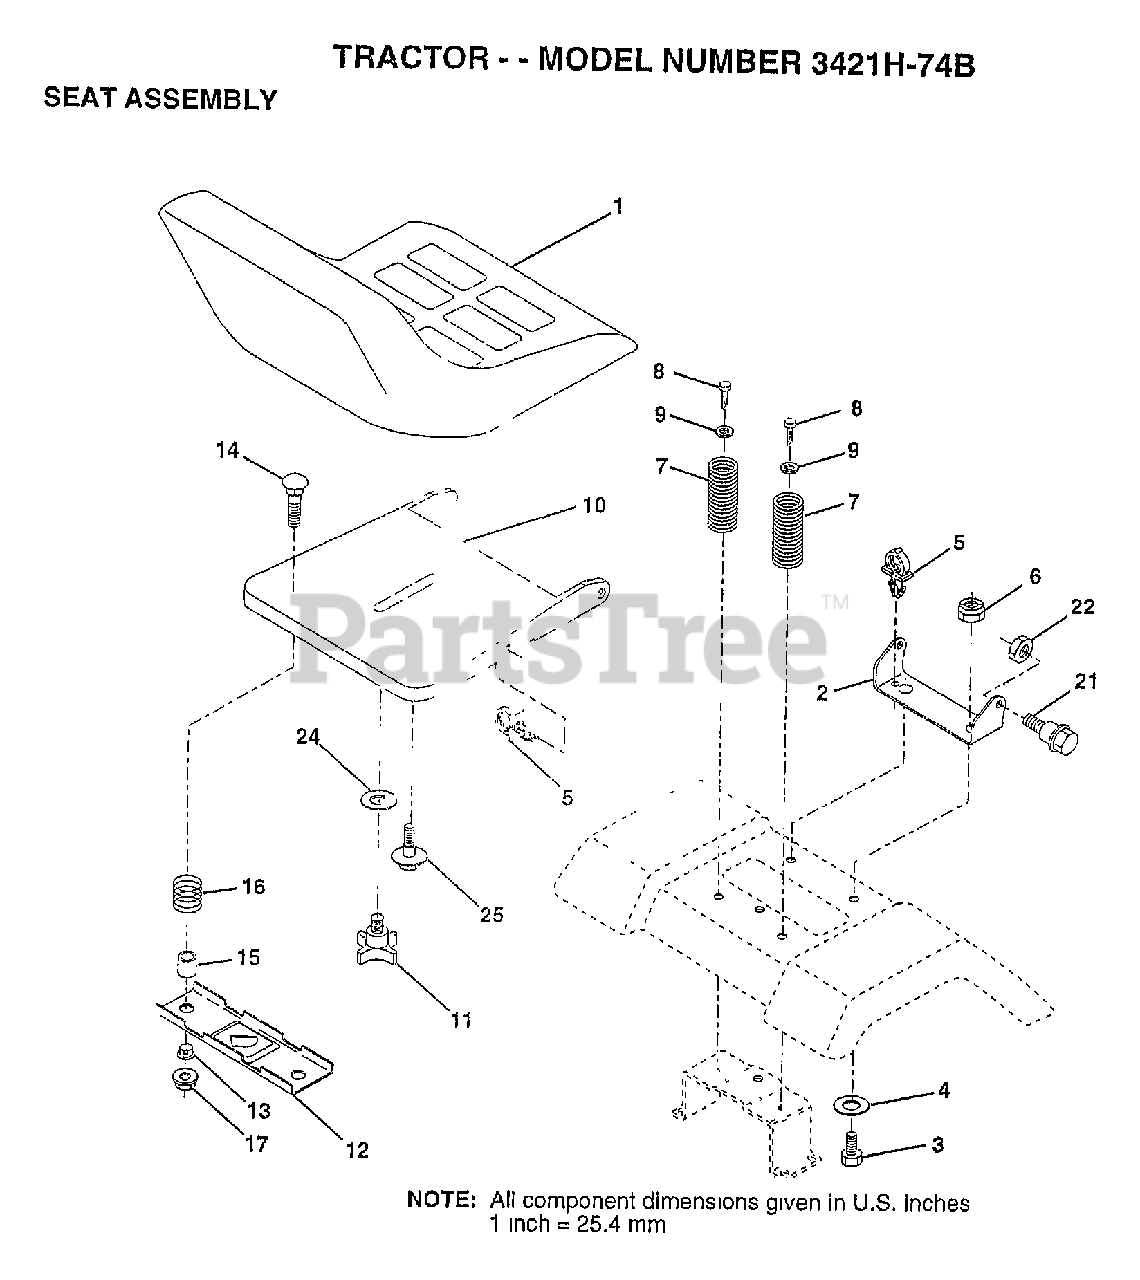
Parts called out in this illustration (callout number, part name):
2	BRACKET PVT SEAT
3	BOLT
4	WASHER PM
5	CLIP.PUSH-IN.HING
6	NUT
7	SPRING COMPRESSIO
8	SCREW GTV
9	WASHER
10	PAN-SEAT
11	"KNOB 1/2"" YT"
12	BRKT SWITCH
13	BUSHING
15	SPACER SPLIT
16	SPRING COMPRESSED
21	"BOLT,SHOULDER"
24	WASHER
25	"BOLT,SHOULDER"
